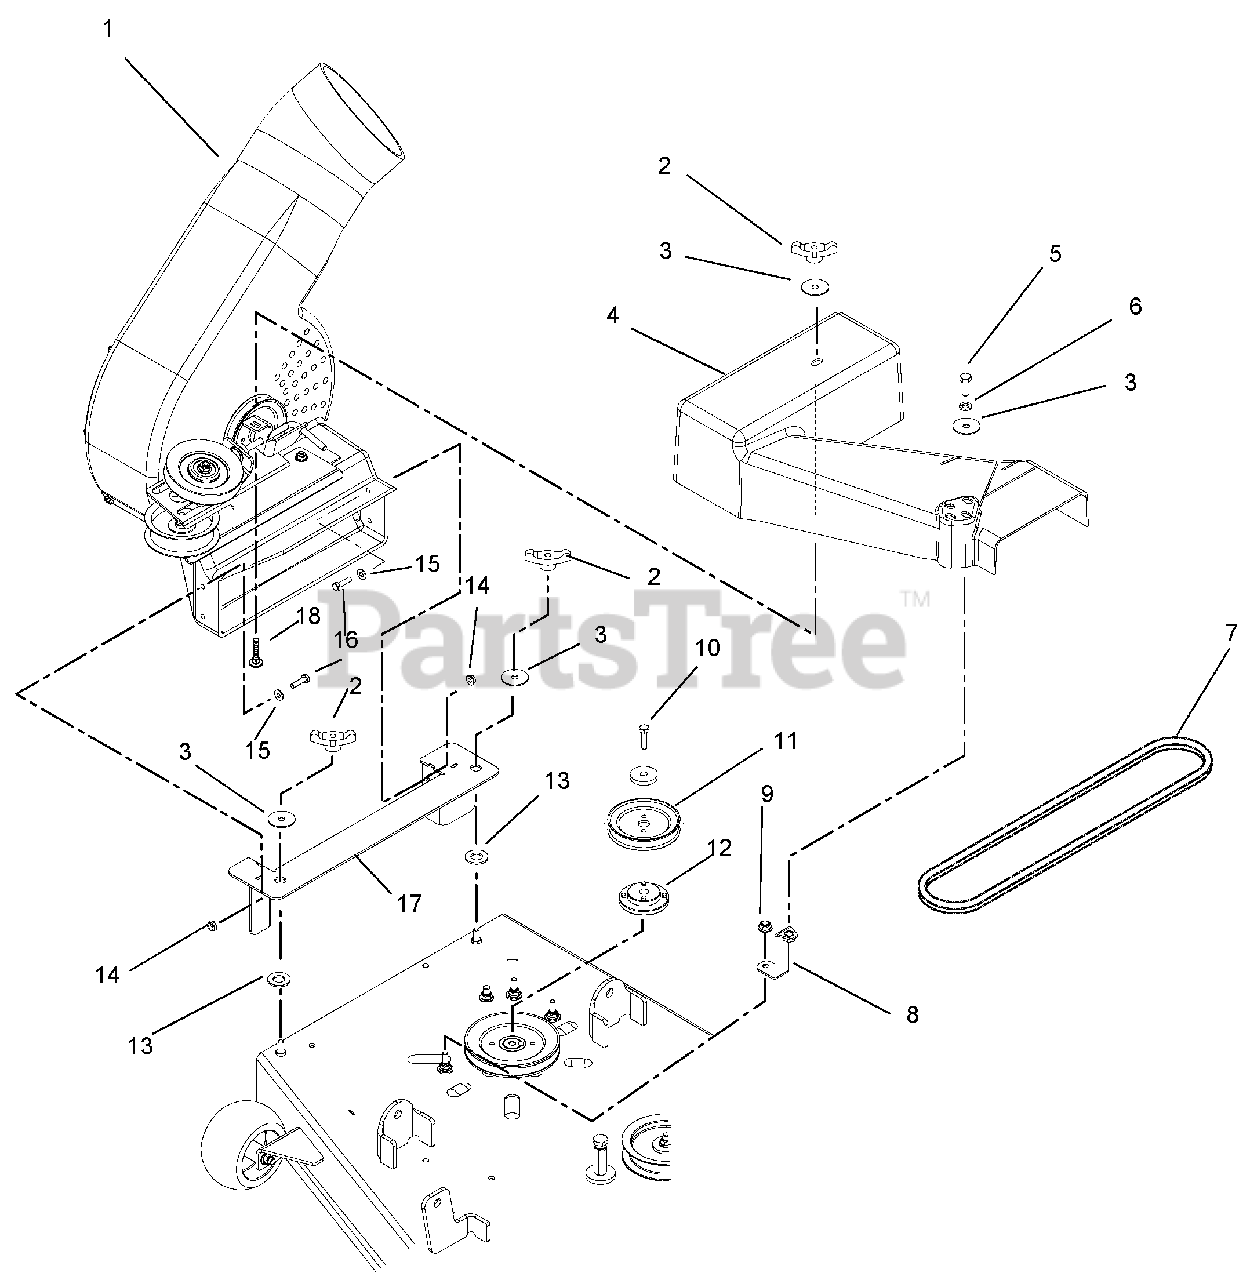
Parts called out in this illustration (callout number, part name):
1	Housing, Blower
2	Knob, Wing .312-18
3	Washer, Flat, Steel.38 x 1.50 x .062
4	Belt Cover, with Decal
5	Bolt, Hex .38-16 x 1.00 – Grade 5
6	Washer, Lock .38
7	V-Belt, 4L Raw Laminated (48-Inch Decks)
7	V-Belt, HA Wrapped (54-Inch Decks)
8	Standoff, XL Blower Cover
9	Nut, Nylon Lock, .312
10	Bolt, Hex .38-16 x 1.75 – Grade 8
11	Sheave, 4.00 Diameter
12	Assembly, Sheave Adapter
13	Washer, Flat, Steel .656 x 1.25 x .10
14	Nut, Locking-Top-Flange .25-20
15	Washer, Flat, Steel .281 x .62 x .065
16	Bolt, Hex .25-20 x 1.00 Grade 5
17	Bracket, Blower Weldment
18	Bolt, Round Head Square Neck, .31-18 x 1.50
